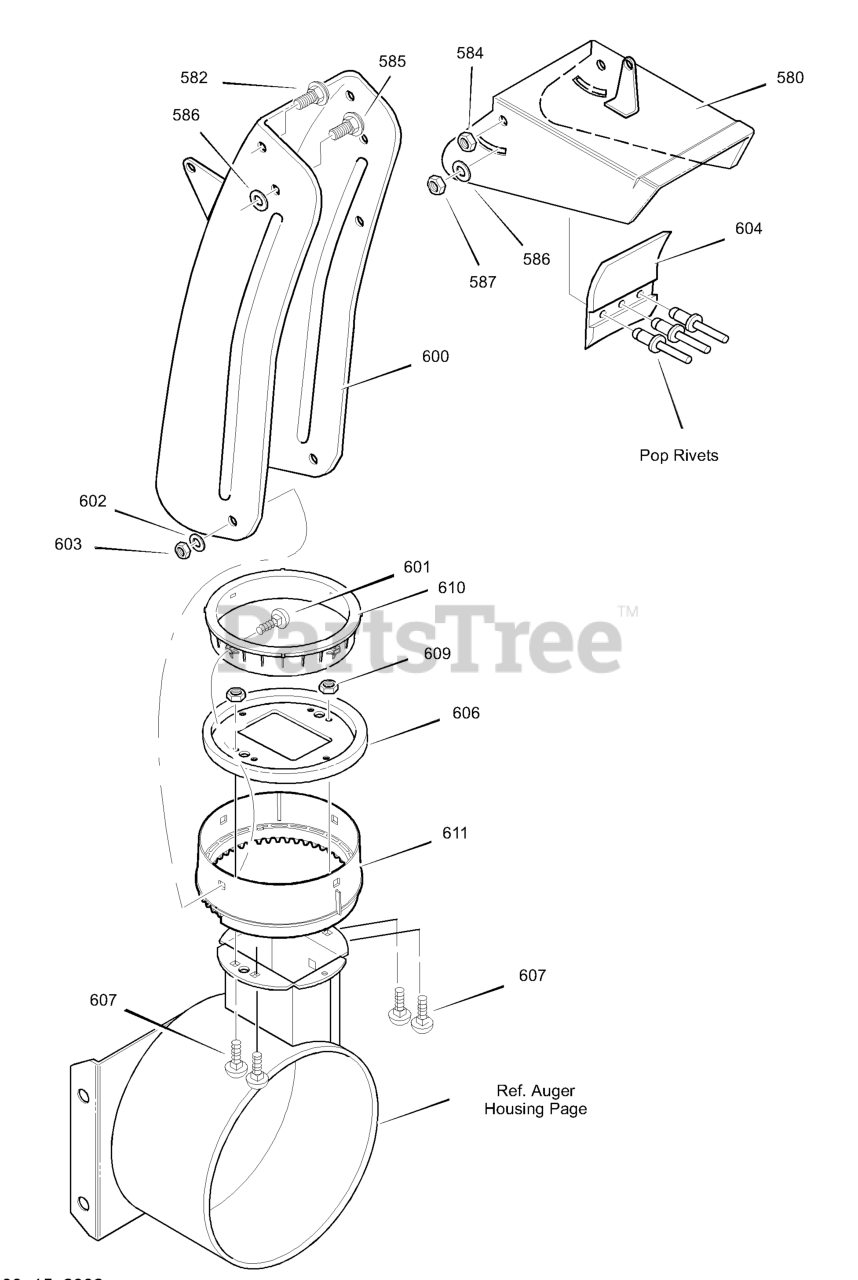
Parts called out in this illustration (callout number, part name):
580	CHUTE, UPPER W/REMOTE
582	SCREW, 5/16-18 x 0.75
584	NUT, 5/16-18
585	SCREW, 5/16-18 x 0.75
586	PLASTIC WASHER
587	NUT, 5/16-18
600	CHUTE, LOWER W/REMOTE
601	BOLT, 5/16-18 x 1.00
602	WASHER, FLAT
603	NUT, 5/16-18
606	CHUTE COLLAR
607	BOLT, 1/4-20 x .75
609	NUT, 1/4-20 NYLOCK
610	RETAINER, RING INNER
611	RETAINER, RING OUTER
